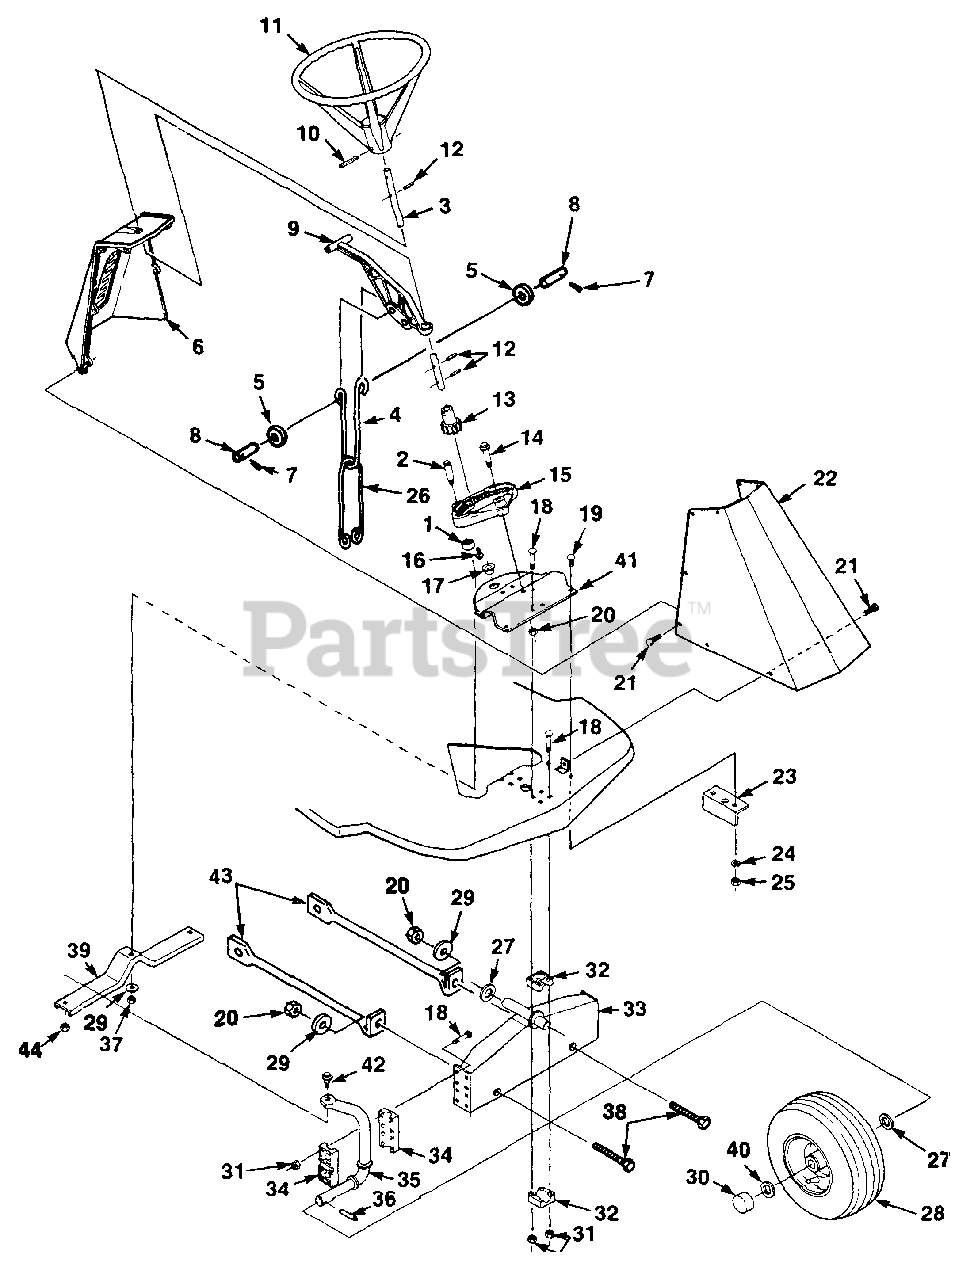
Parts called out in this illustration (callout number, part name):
1	BUSHING- Ball
2	STUD- Steer
3	SHAFT- Steering
4	LINK- Front Lift
5	WASHER- Flat 1/2
6	PANEL- Console
7	PIN- Cotter 1/8 x 3/4
8	PIN- Retainer
9	HANDLE- Lift
10	PIN- Roll 1/4 x 2
11	WHEEL- Steering
13	PINION- Steering
14	BOLT- Shoulder 3/8-16 x .125
15	SECTION- Steering
16	SCREW 1/4-20 x 1/2
18	BOLT- 1/4-20 x 1 3/4 Carr.
19	BOLT- 1/4-20 x 3/4 Carr. Sq. Nk
20	NUT- 3/8-16 C'lock
21	BOLT- 1/4-14 x .44 Swedge form
22	SUPPORT- Steering
24	WASHER- Lock 1/4
25	NUT- 1/4-20 hex
26	LINK- Lower Lift
28	WHEEL & TIRE
29	WASHER- Plain (Flat 3/8)
31	NUT- 1/4-20 hex c'lock
32	BEARING- Front axle
33	AXLE- Front
34	BEARING- Wheel spindle
35	SPINDLE- L.H. Wheel
36	PIN
37	NUT- C'Locking-hex 3/8-24
38	SCREW- 3/8-16 x 5/8
39	BRACKET- Steering
41	BRACKET- Reinforcement Steering
42	BOLT- Shoulder
43	SUPPORT- Front Axle
44	NUT-Hex 5/16-18
